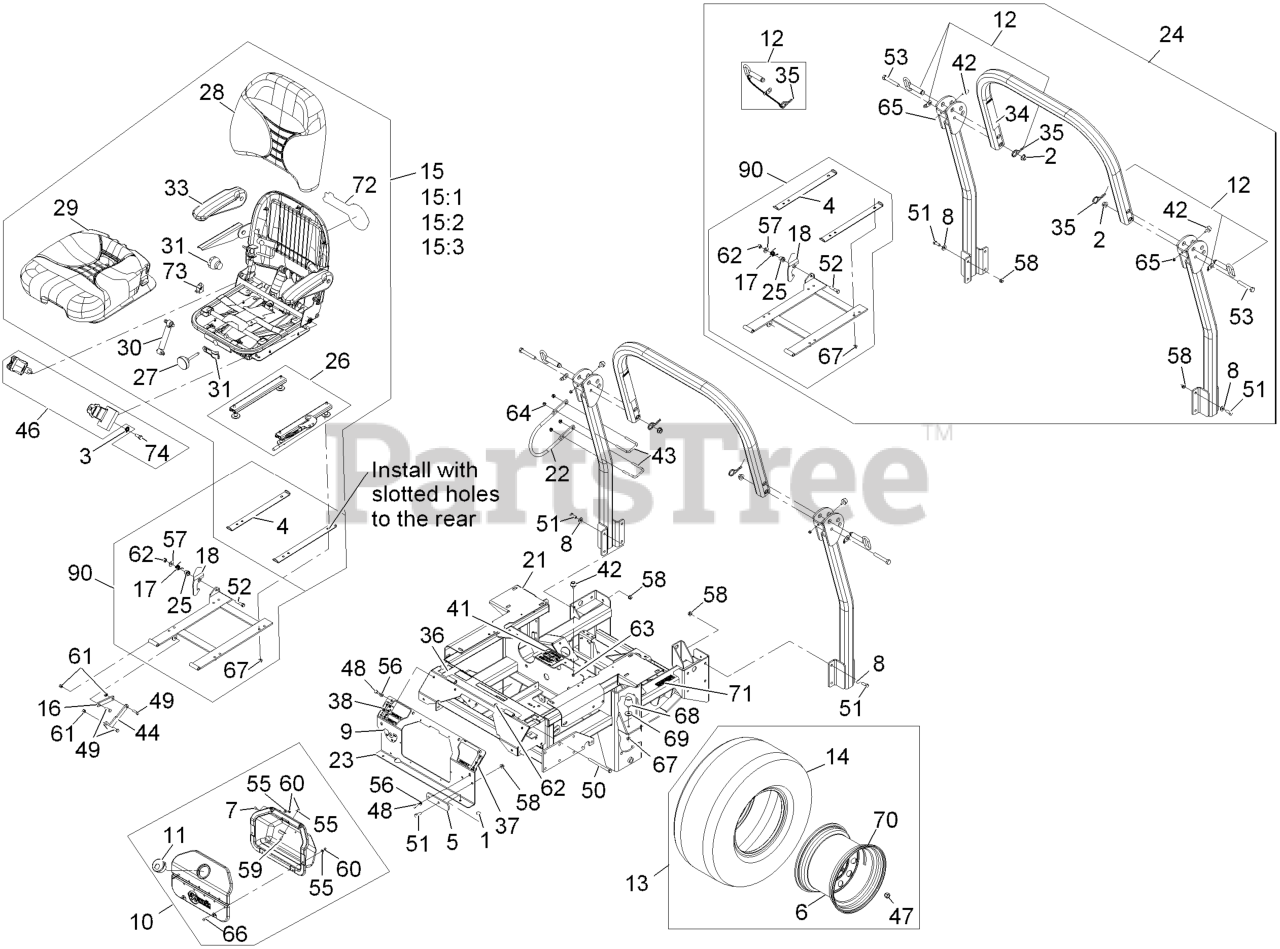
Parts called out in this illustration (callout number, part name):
3	WASHER-SPRING
4	STOP/SPACER-SEAT
5	STOP-BRAKE, PARK
7	SCREW-HEAD, TRUSS
8	WASHER-BELLEVILLE
9	DECAL-VALVE, FUEL
10	ASM,CUBBY
11	LATCH,CUBBY
12	PIN-FOLD, ROPS
13	WHEEL AND TIRE ASM
15:1	SPRING AND SADDLE KIT
15:2	BACK PANEL KIT
15:3	WEIGHT ADJUST KIT
16	LINK-STOP, SEAT
17	SPRING-TORSION, LATCH
18	CATCH-LATCH, SINGLE
21	ASM,KDXS ENGINE DECK W/DE
23	ASM, CONSOLE W/DECALS
24	KIT, 06 XS ROPS
25	BUSHING-LATCH, SEAT
26	SEAT TRACK KIT
27	KNOB KIT
28	BACK CUSHION KIT
29	BOTTOM CUSHION KIT
30	SHOCK ABSORBER KIT
31	WEIGHT INDICATOR KIT
33	PAD-ARMREST
34	DECAL-WARNING, FOLDING RO
35	HAIRPIN
36	DECAL-CONSOLE, TOP
37	DECAL,PARK BRAKE
38	DECAL,DECK HEIGHT
41	DECAL,WARNING
42	BUMPER-RUBBER
44	LINK-STOP, SEAT
46	RETRACTABLE SEATBELT KIT
47	NUT-LUG
48	SCREW-HH
49	SCREW-HH
50	SCREW-HH
51	SCREW-HH
52	SCREW-HH
53	SCREW-HH
55	WASHER-FLAT
56	WASHER-PLAIN
57	WASHER-FLAT
58	NUT-HHF, WHIZ
59	SCREW-PPH
60	NUT-LOCK, NI
61	NUT-LOCK, NI
62	NUT-LOCK, NI
63	NUT-LOCK, NI
64	NUT-LOCK, NI
65	NUT-LOCK, NI
68	BUMPER-RUBBER
71	DECAL-ARRESTER, SPARK
72	DECAL,EXMARK LOGO
73	SWITCH-BAIL
74	SCREW-HH
90	KIT,SEAT FRAME SERVICE
